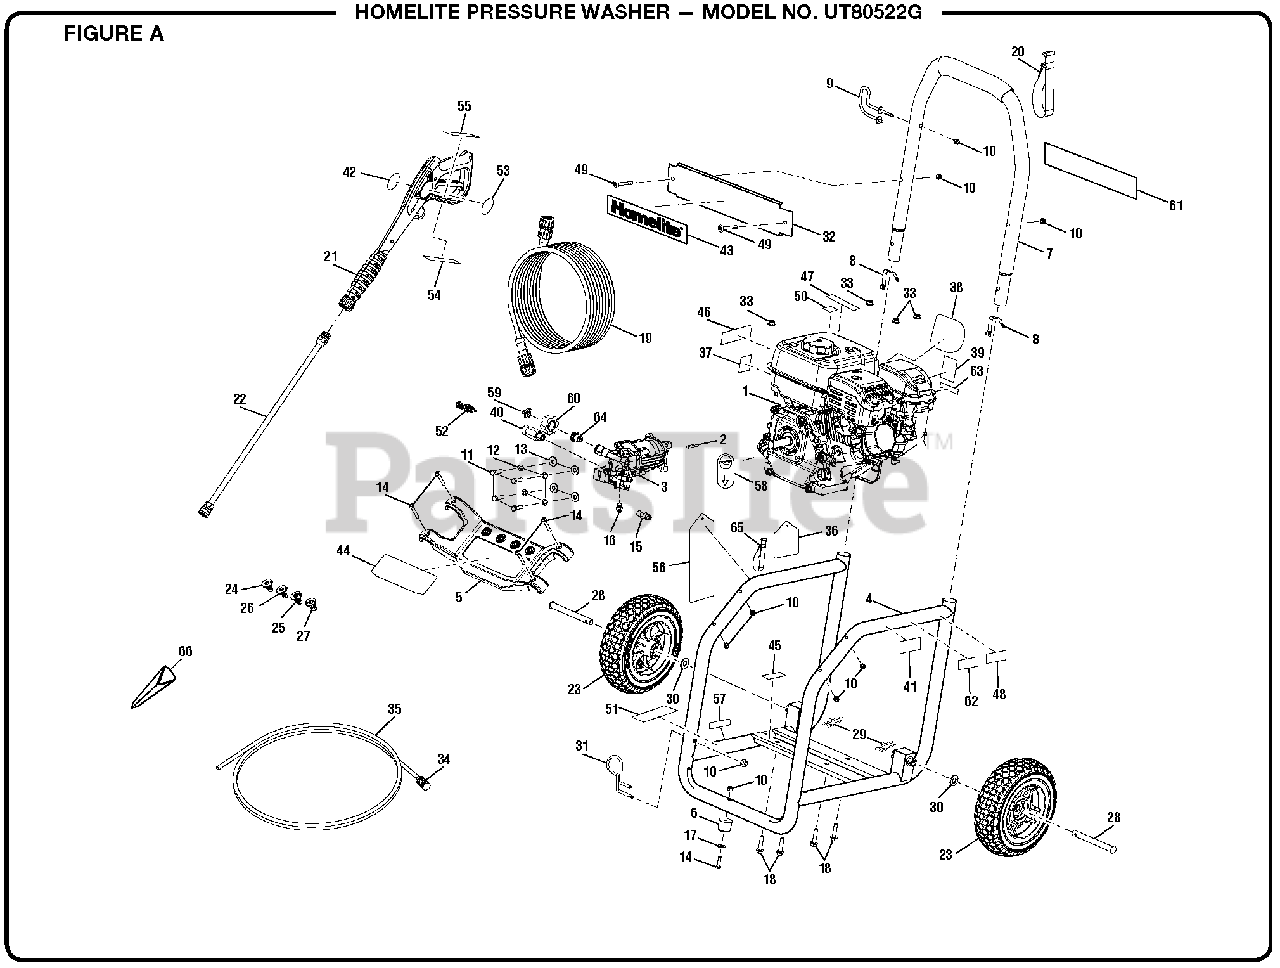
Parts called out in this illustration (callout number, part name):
1	Engine (Rato 180cc Horizontal Shaft, EPA III)
2	Output Shaft Key
3	Pump
4	Main Frame
5	Nozzle Holder
6	Rubber Foot
7	Handle Assembly
8	Lock Button w/Spring Clip
9	Wand Holder (Upper)
10	Lock Nut (1/4-20)
11	Bolt (5/16-24 x 27 mm, Hex Hd.)
12	Lock Washer (5/16 in.)
13	Washer (5/16 in.)
14	Screw (1/4-20 x 2.0 in.)
15	Thermal Release Valve
16	Detergent Suction Kit
17	Washer (1/4 in.)
18	Bolt (M8 x 36 mm, Hex Flange Hd.)
20	Hook and Loop Strap
21	Trigger Handle
22	Extension Wand
23	Wheel Assembly (10 in. x 3 in.)
24	Nozzle, 0deg
25	Nozzle 40deg
26	Nozzle 25deg
27	Soap Nozzle
29	Hitch Pin
30	Washer (1/2 in.)
31	Wand Holder (Lower)
32	Front Panel
33	Lock Nut (M8 x 1.25)
35	Chemical Siphon Tube
36	Nozzle Instructions Hangtag
37	Engine Label (On-Off)
38	Recoil Label
39	Choke Label
40	Outlet Tube
41	Hot Surface Label
42	Trigger Handle Logo Label
43	Homelite Label
44	Performance Label
45	Add Oil Label
46	Danger Label
47	E85 Label
48	Homelite Inquiries Label
49	Bolt (1/4-20 x 43 mm, Torx T-30)
50	No Oil to Gas Label
51	Combustion Label
52	Unloader Assembly
53	Trigger Handle Warning Label (Eng)
54	Warning Label (Fr/Sp)
55	Trigger Handle Label
56	Danger Hangtag
57	Lubricant Label
58	Dipstick Hangtag
59	Filter Screen
61	Quick Start Label
62	EMC Label
63	Fuel On/Off Label
65	Detergent Suction Hose Velcro Strap
